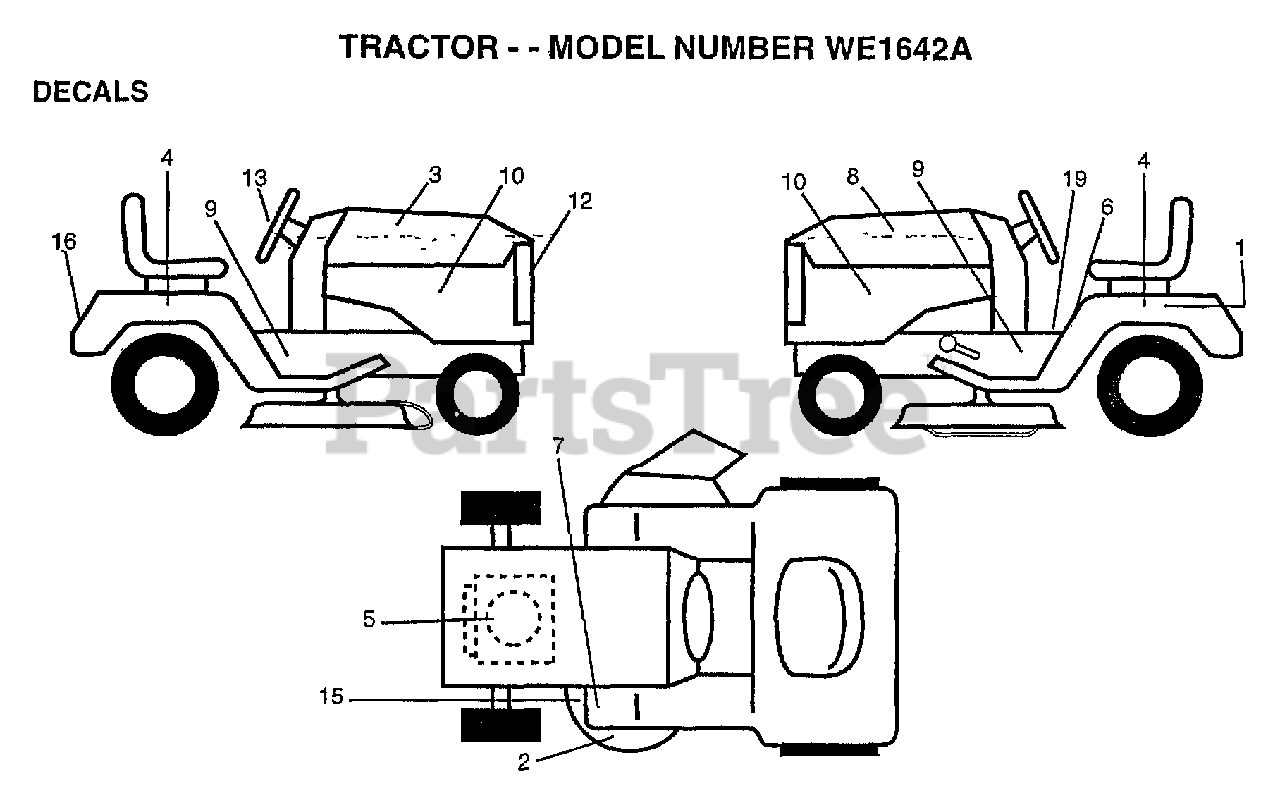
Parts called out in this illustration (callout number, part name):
1	DECAL.BATRY.3-3908
3	"DECAL HOOD,RH"
4	DECAL.FENDER.WIZ
5	DECAL, HP ENGINE
6	"DECAL DANGER,FEND"
8	DECAL HOOD LH
10	"DECAL PANEL,SIDE"
12	"DECAL GRILLE,LENS"
13	"DECAL INS,STRG WH"
15	DECAL
16	DECAL-FENDER
19	"DECAL INST,SADDLE"
